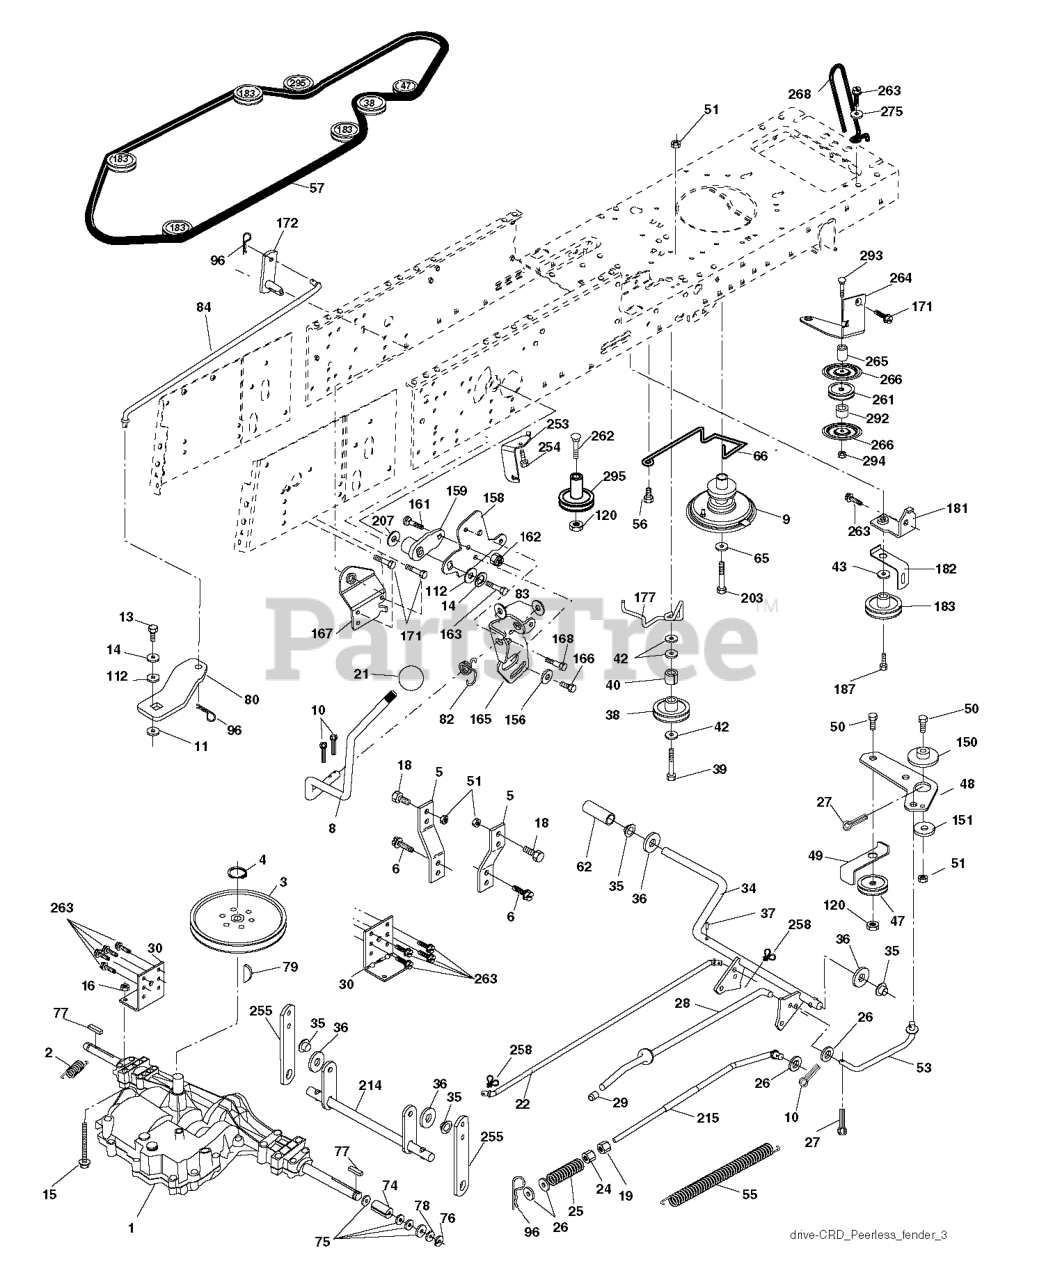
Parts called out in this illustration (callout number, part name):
2	SPRING,BRAKE RETURN
3	PULLEY
4	RETAINING RING LT
5	STRAP TORQUE
6	SCREW 5/16"
8	ROD SHIFT FENDER ADJUST LT
10	PIN COTTER
11	WASH-SHFT PLT LT
13	BOLT 1/4-28X3/4
14	LOCKWASHER
15	BOLT HEX 5/16-18 GR 5
16	NUT.71038.31-18.HEX.NYLOCK
19	NUT
21	KNOB T (1/2-HOLE)
22	ROD
24	NUT
25	SPRING ROD LT
26	WASHER
27	COTTER PIN
28	ROD, PARKING BRAKE
29	PLUNGER CAP
30	BRKT, MOUNT TRNSAXLE
34	SHAFT, FOOT PEDAL
35	BEARING.NYLON
37	DRIVE PIN
38	PULLEY.FLAT
42	WASHER
47	IDLER PULLEY
48	BELLCRANK, CLUTCH
49	RETAIN BELT
50	BOLT.3/8-16X1.50
53	LINK.CLUTCH.7.66.2005
55	SPRING, RETURN LT
56	SCREW.3/8-16
57	V-BELT.KEV.111"
62	PEDAL COVER T
65	LOCKWASHER
66	KEEPER BELT ENGINE
74	SPACER AXLE
77	SQUARE KEY
79	KEY STD (1373) DANA
82	SHIFT SPRING
83	WASHER
96	RETAINER M
120	NUT LOCK FLG 3/8-16 UNC
150	BUSHING.BELLCRANK.GRD.DR
151	WASHER 12/32X2X10GA
156	WASHER.SRRTD.5/16
158	BRACKET
159	RB HUB.SHIFT
161	BOLT
162	NUT.CROWNLOCK.1/4
165	RP BRACKET
166	CAPSCREW.HXHD.FLG.5/16-18X.625
167	BRACKET.SUPT.SHIFT.CRD
168	BOLT.SHOULDER.5/16-18X
172	SHAFT
181	BRACKET
182	BELT GUIDE
183	PULLEY.V-IDLER.GRND.DR
187	BOLT.5/16-18X1.25
203	BOLT.HEX.7/16-20 X 5
207	WASHER NYL
214	LEVER
254	SCREW 3/8-16X1
255	SHAFT
258	CLIP RETAINER
261	FLAT IDLER PULLEY
263	SCREW, 3/8-16X3/4
266	PROTECTOR
268	GUARD MUFFLER
275	WASHER
292	SPACER
293	BOLT.RDHD SQNK 3/8-16 X 3-1/2
294	NUT.HEX.3/8-16
295	PULLEY IDLER COMPOSITE
